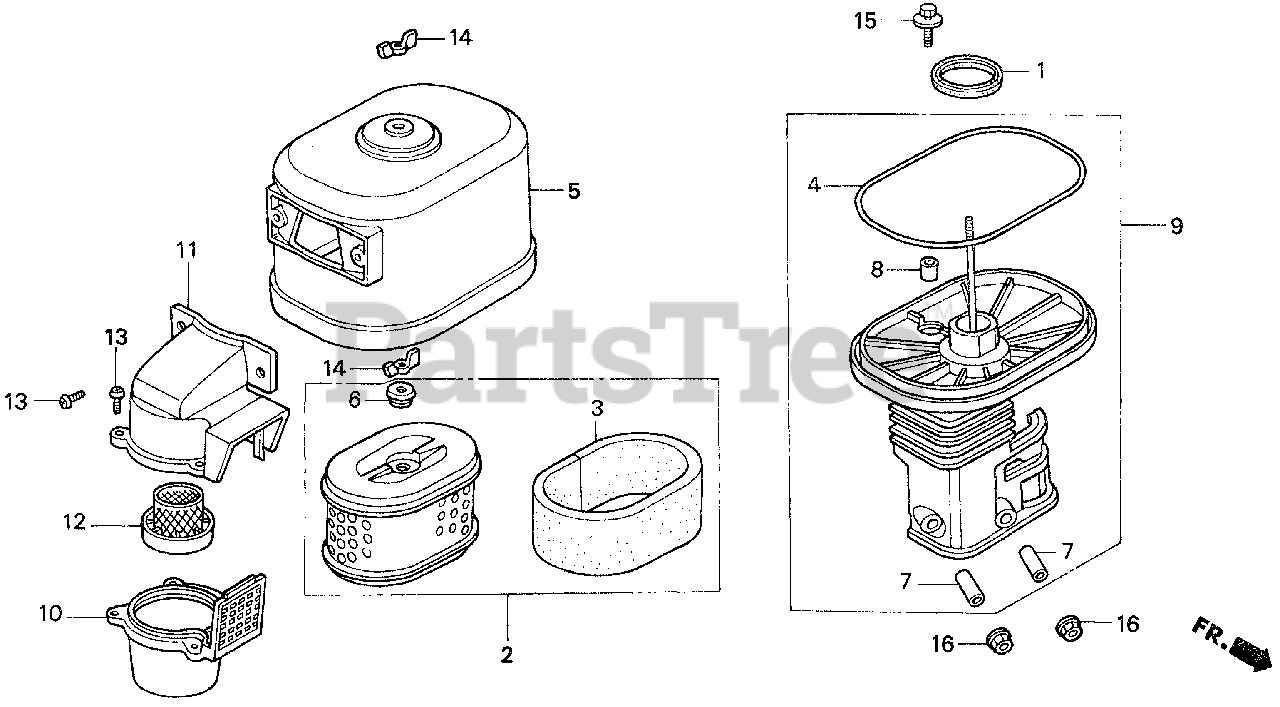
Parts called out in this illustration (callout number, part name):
1	GASKET, ELBOW
2	ELEMENT, AIR CLEANER
3	FILTER (OUTER)
4	SEAL, AIR CLEANER COVER
5	COVER, AIR CLEANER (CYCLONE)
6	GROMMET, AIR CLEANER
7	COLLAR, AIR CLEANER
8	COLLAR B, AIR CLEANER
9	ELBOW, AIR CLEANER
10	CASE, PRE AIR CLEANER
11	CAP, PRE AIR CLEANER
12	GUIDE, PRE AIR CLEANER
13	SCREW, PAN (5X16.5)
14	WINGNUT, TOOL BOX SETTING
15	BOLT-WASHER (6X22)
16	NUT, FLANGE (6MM)
